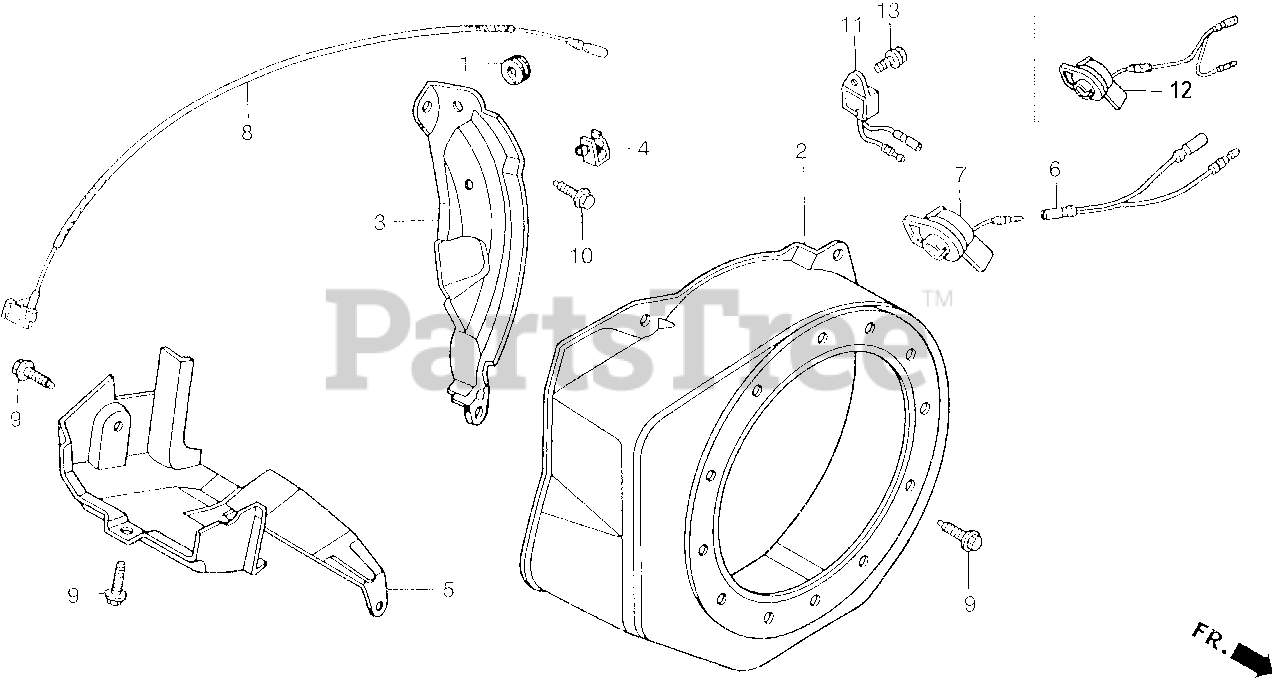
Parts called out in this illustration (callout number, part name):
1	GROMMET, ADJUSTING COVER
2	COVER, FAN *R280* (POWER RED)
3	PLATE, SIDE (OIL ALERT)
4	CLAMP, CORD
4	CLIP, HARNESS
6	SUB-HARNESS
7	SWITCH ASSY., ENGINE STOP
8	WIRE, STOP SWITCH (370MM)
9	BOLT, FLANGE (6X12) (CT200)
10	BOLT, FLANGE (6X20) (CT200)
11	ALERT UNIT, OIL
13	BOLT, FLANGE (6X8)
